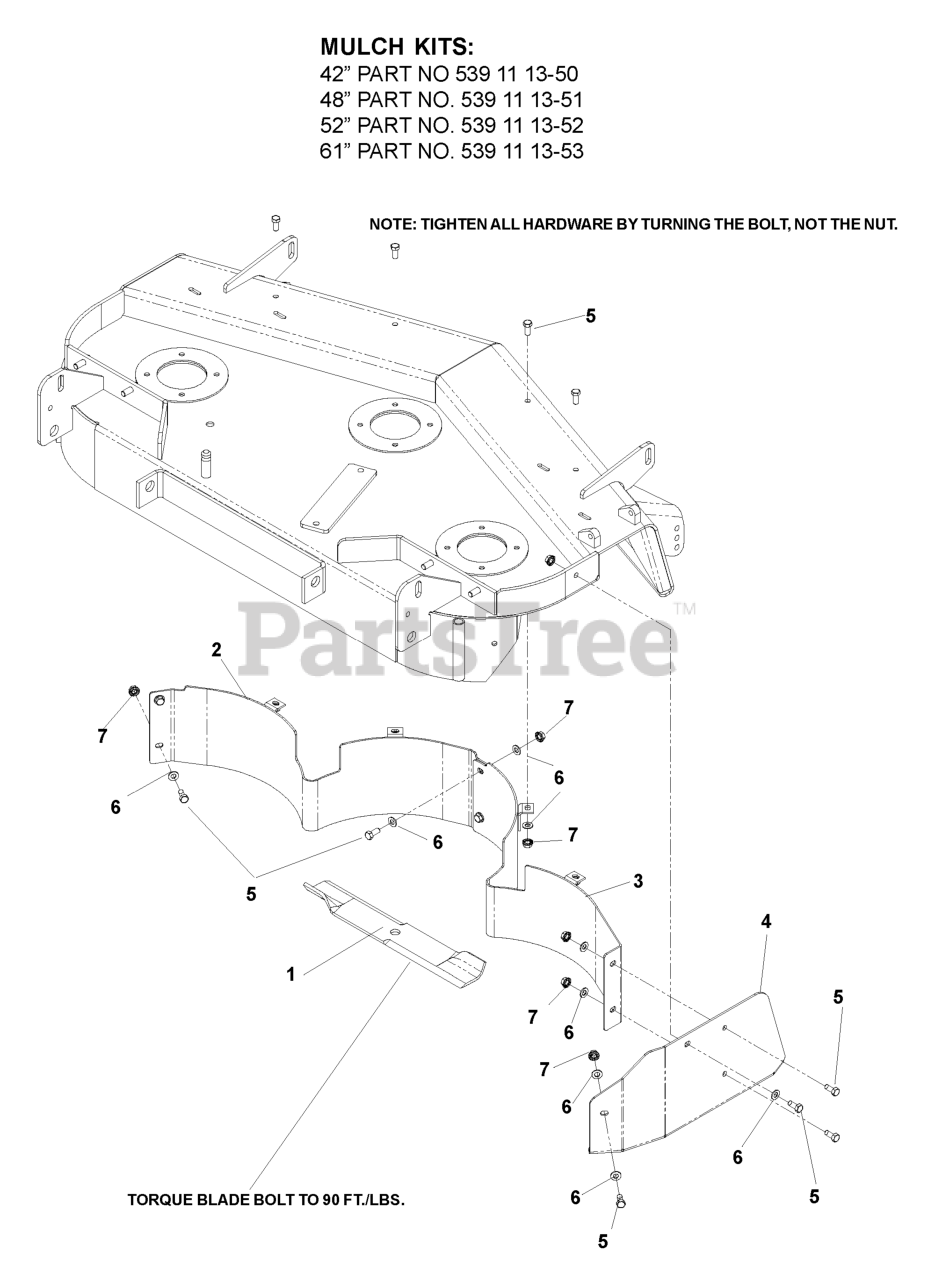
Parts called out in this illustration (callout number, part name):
1	BLADE MULCH 14-7/8"
1	BLADE MULCH 16-1/4"
1	BLADE MULCH 18"
1	BLADE MULCH 21"
2	MULCH BAFFLE, LEFT, 42
2	BAFFLE WLDMT 42" LH
2	BAFFLE WLDMT, 52" L.H.
2	BAFFLE WLDMT, 61" L.H. MULCH
3	BAFFLE WLDMT, 42" R.H. MULCH
3	BAFFLE WLDMT 48 RH
3	BAFFLE WLDMT, 52" R.H. MULCH
3	BAFFLE WLDMT 61" R.H. MULCH
4	MULCH CAP 42"
4	MULCH CAP 48
4	MULCH CAP 52
4	MULCH CAP 61
5	HCS 5/16C X 3/4
6	FLAT WASHER 5/16 SAE
7	NUT 5/16C WHIZ
539111350	MULCH KITS 42"
539111351	MULCH KITS 48"
539111352	MULCH KITS 52"
539111353	MULCH KITS 61"
